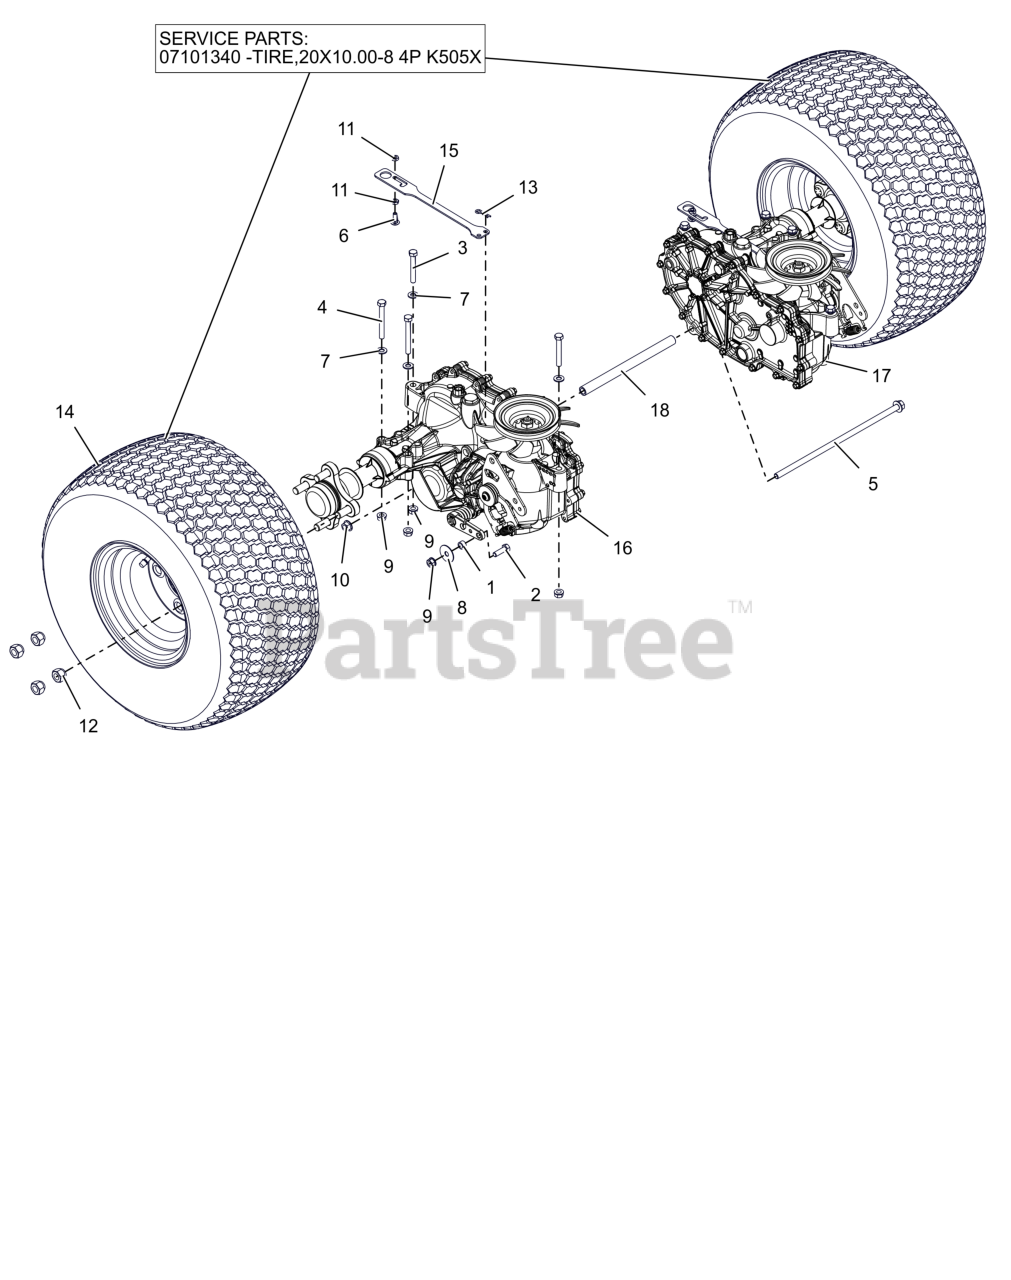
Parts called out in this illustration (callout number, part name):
1	SPCR- SLV .344 X .500 X .283
1	TIRE, 20X10.00-8
2	BLT,HEX .31-18X1.00 G5 ZCC
3	BLT, HEX .31-18X2.25 G5 ZCC
4	BLT, HEX .31-18X2.75 G5 ZCC
5	BLT, HEX-FLG 0.375-16X11.5 GR5 ZC120
6	BLT, RHSN .25-20X.750 G5 ZCC
7	WSHR,FLT .344X.688X.065 ZCC
8	WSHR, FLT .347X1.254X.048 ZCC
9	NUT,LK-CTR-FLG .31-18 GF ZCC
10	NUT-LK-CTR-FLG .375-16 GF ZCC
11	NUT-LK-CTR-JAM .250-20 GB ZCC
12	NUT, WHEEL .50-20 ZCC
13	PIN, HAIR #213 .08X1.19 ZCC
14	ASM- WHL/TIRE 20X10-8 K505
15	LEVER-TRANSAXLE DMP VALVE(BLK)
16	TRANSAXLE- HG 48/52 LH
17	TRANSAXLE- HG 48/52 RH
18	SPCR- .390 X .750 X 8.50
